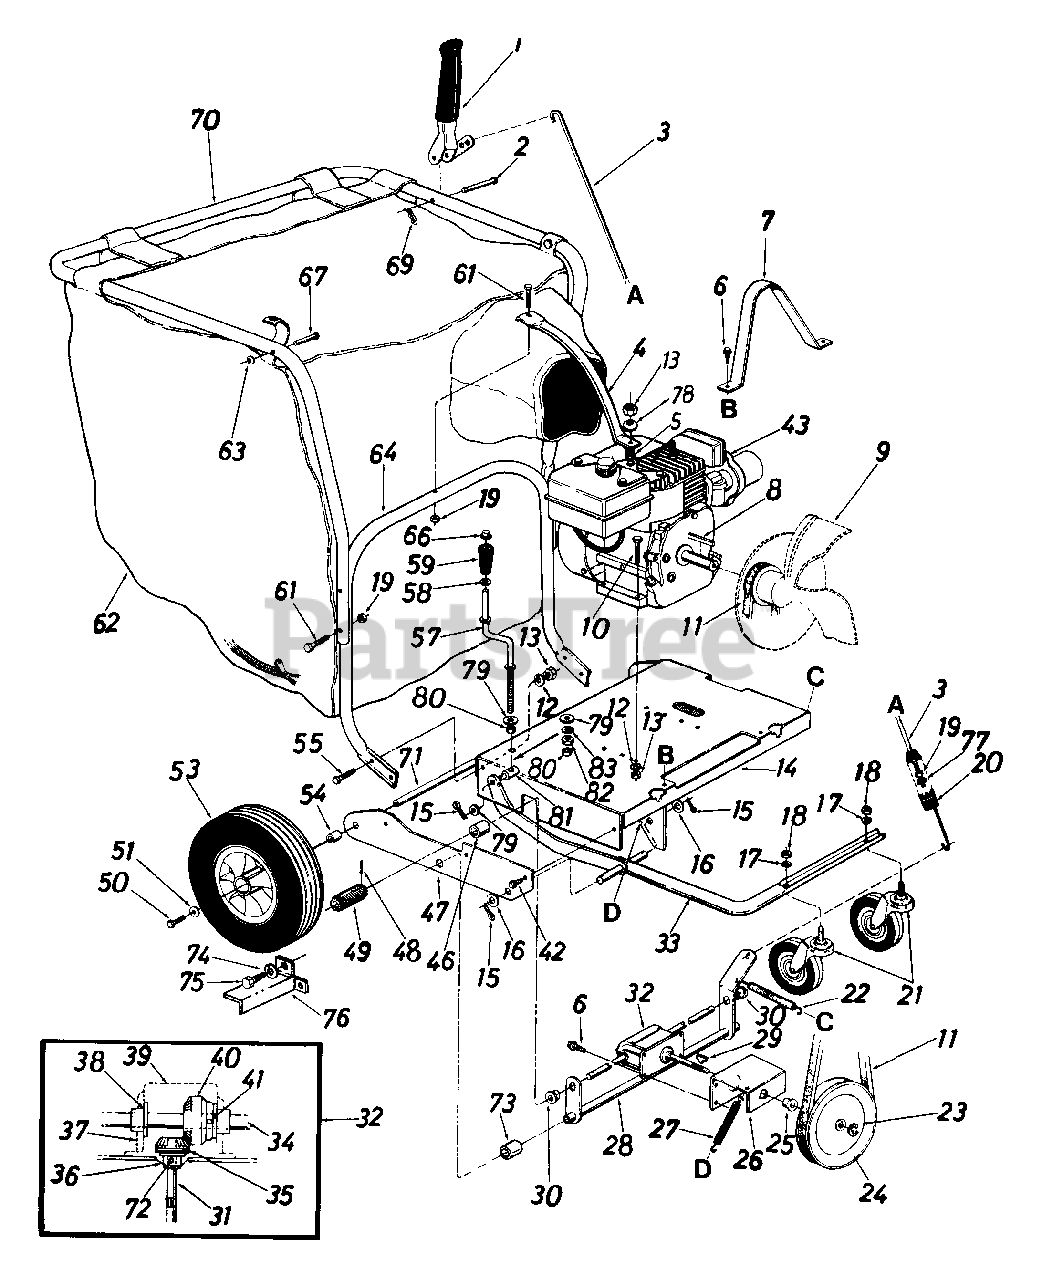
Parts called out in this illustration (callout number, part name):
1	Clutch Grip Ass'y.
2	Clevis Pin .375" Dia. x 1.88"
3	Clutch Rod 32" Lg.
4	Handle Brace
5	Part of Engine
6	Hex Wash. Hd. AB-Tap Scr. 1/4" x .62" Lg.
9	Air Vane Plate Ass'y. w/Pulley
10	Hex Bolt 5/16-18 x 1.5" Lg.
11	"V"-Belt
12	L-Wash. 5/16" I.D.
13	Hex Nut 5/16-18 Thd.
16	FI-Wash. .63" I.D. x 1.25" O.D.
17	L-Wash. 1/2" I.D.
18	Hex Nut 1/2-13 Thd.
19	Hex Cent. L-Nut 1/4-20 Thd.
20	Extension Spring .78" O.D. x .75" Lg.
21	Swivel Caster Wheel 5" Dia. x 1.25"
22	Extension Spring .38" O.D. x 7.50" Lg.
23	Snap "E"-Ring .50" Dia. Shaft
24	"V"-Pulley 5/8" x 6.50" O.D.
25	Flange Bearing .502" I.D.
28	Clutch Bracket Ass'y.
29	#2 Woodruff Key 3/32" Dia. x .81" Lg.
30	Hex Flange Bearing Bronze .625" I.D.
31	Pinion Shaft .50" Dia. x 5"
32	Gear Box Ass'y. Comp.
35	Bevel Gear .50" I.D. x 14 Teeth
36	Flange Bearing .503" I.D.
37	Gear Box
38	Flange Bearing .630" I.D.
39	Gear Box Cover
40	Bevel Gear .62" I.D. x 28 Teeth
41	Spring Pin Spiral 3/16" Dia. x 1.25" Lg.
42	Hex Wash. Hd. AB-Tap Scr. 5/16" x .75" Lg.
43	Engine
46	Spacer .63" I.D. x .88" O.D. x .56" Lg.
49	Drive Pinion
50	Hex Locking Bolt 5/16-24 x .62" Lg
51	FI-Wash .34" I.D. x .87" O.D
53	Wheel Ass'y. Comp. 12" x 3"
54	Spacer .63" I.D. x 1.0" O.D. x .94" Lg.
55	Hex Bolt 5/16-18 x .75" Lg.
57	Height Adjustment Crank
58	FI-Wash .385" I.D. x .62" O.D.
59	Crank Knob
61	Hex Bolt 1/4-20 x 1 75" Lg
62	Vacuum Bag - Felt
63	Push Speed Nut .25" Dia. Stud
67	Stud Pin .250" Dia. x 1.75"
69	Internal Cotter Pin 3/8" Dia.
70	Upper Handle
71	Rear Axle
72	Spring Roll Pin 5/32" Dia. x 1.12
73	Spacer 82" I.D. x 1.0" O.D. x .305 Lg.
74	L-Wash. .265" I.D.
75	Hex Self-Tap Scr. 1/4" x 3/8" Lg.
78	Belleville Washer
79	Fl-Wash .35" I.D. x .87" O.D.
80	Spacer .38" I.D. x .50" O.D. x .18" Lg.
81	Ferrule 3/8-8 x .38" Dia.
82	Hex Nut 3/8-8 Thd.
83	L-Wash 3/8" I.D.
